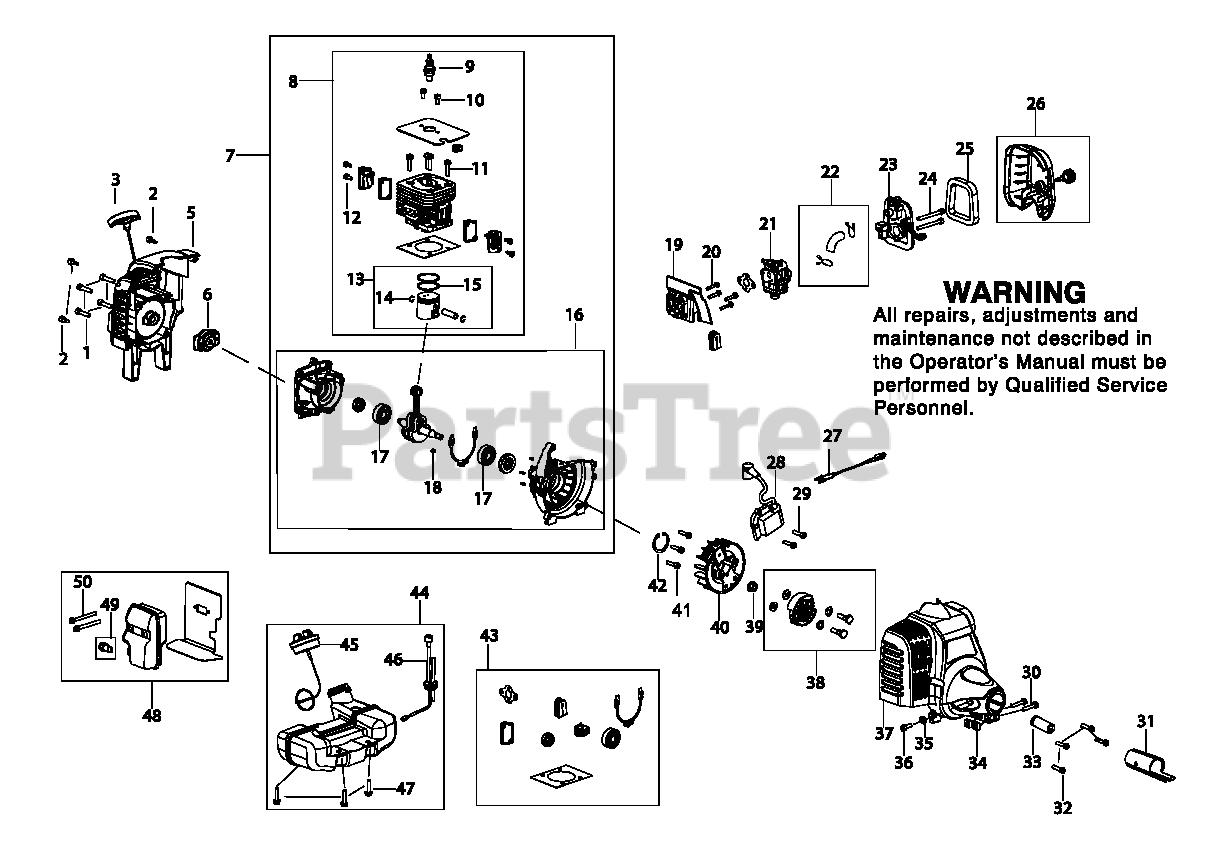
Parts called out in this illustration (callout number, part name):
1	SCREW KIT 4 PACK
3	ROPE & HANDLE KIT
5	STARTER ASSY
6	PAWL ASSY
7	SHORT BLOCK KIT ASSY LT30
8	CYLINDER & PISTON KIT
9	Spark Plug, RZ7C
10	SCREW (4-PACK)
11	SCREW (4-PACK)
12	SCREW 4 PACK
13	PISTON RING KIT
15	PISTON RING
16	C'CASE & C'SHAFT KIT
17	BEARING (2-PACK)
18	KEY 6221-830301
20	SCREW (4-PACK)
21	CARBURETOR
22	INTAKE TUBE KIT
23	AIR BOX BASE ASSY
26	AIR BOX COVER ASSY
27	COIL WIRE
28	IGNITION MODULE
37	FAN HSG ASSY KIT
38	CLUTCH ASSY
40	FLYWHEEL
43	GASKET KIT
44	FUEL TANK ASSY
45	ASSEMBLY
46	KIT FUEL LINE ASSEMBLY
48	MUFFLER ASSY
49	KIT
50	SCREW (2-PACK)
